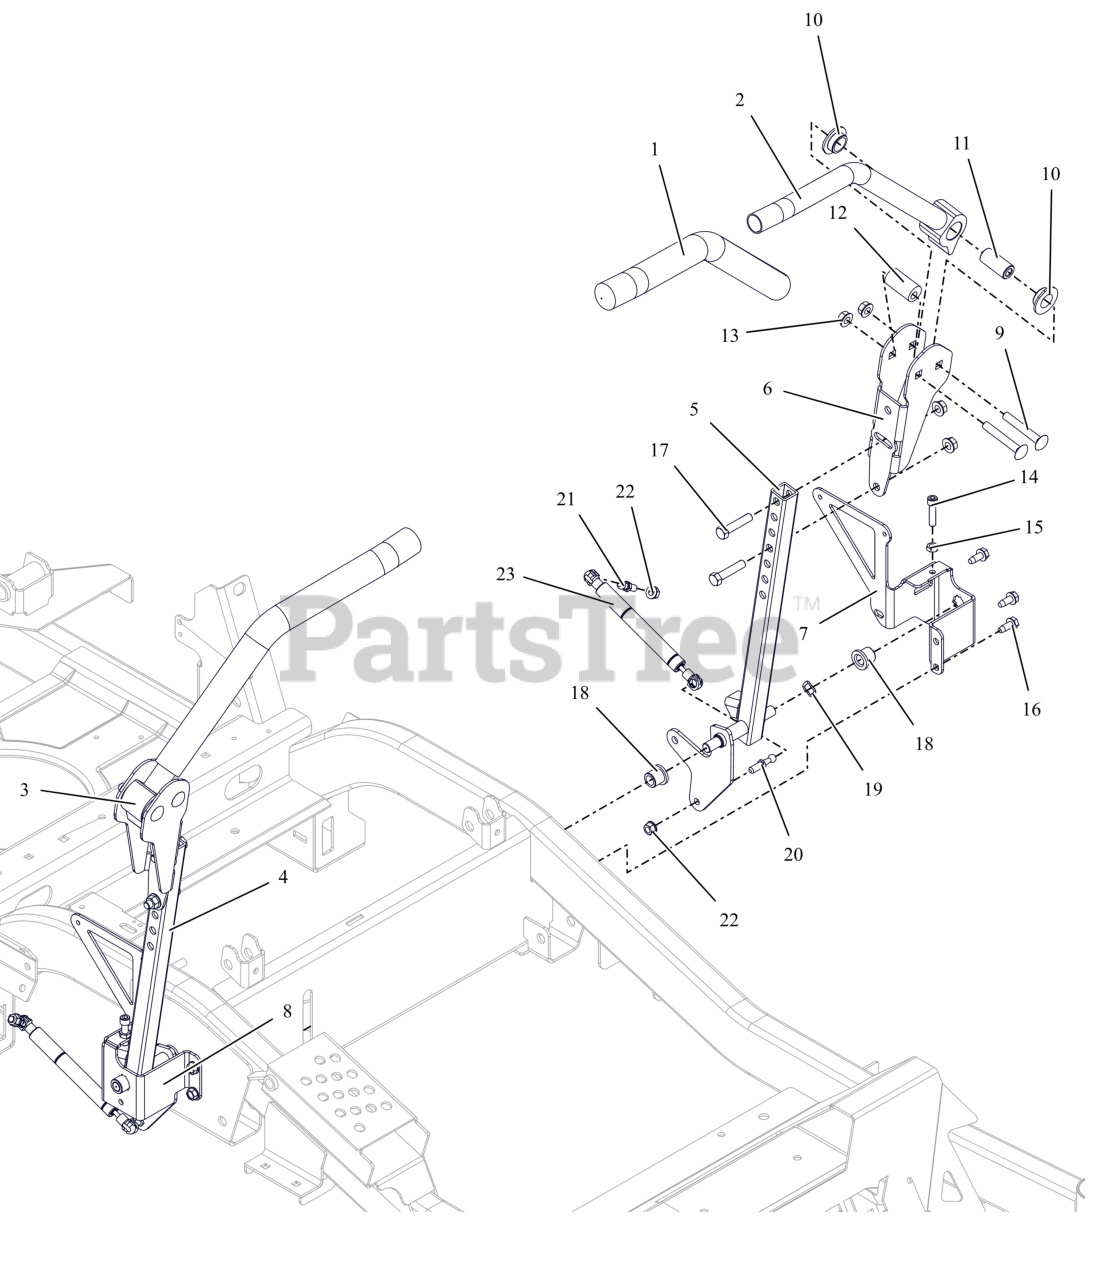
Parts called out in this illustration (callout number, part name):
1	GRIP, HANDLEBAR
2	WLDMT, CONTROL HANDLE (RED)
3	WLDMT, CONTROL HANDLE (RED)
4	WLDMT, STEERING RH (RED)
5	WLDMT, STEERING -LH (RED)
6	BRKT, ADJ UPPER CONTROL ARM (RED)
7	BRKT, STEERING ARM MOUNTING -LH (RED)
8	BRKT, STEERING ARM MOUNTING- RH (RED)
9	BLT, RHSSN.38-16X2.50 G5 ZCC
10	BSHG, FLANGED .762 X 1.48 X .44 IGLIDER
11	SPACER, STEERING ARM
12	BSHG, ECCENTRIC.406X.875X1.625
13	NUT-LK-TOP-FLG .38-16 ZC120
14	SCR, SKH .312-18X1.25 GR8 ZC120
15	NUT-JAM .312-18 G2 ZCC
16	SCR,TAP .312-18X.75 HWH TR ZCC
17	BLT, HEX .38-16X1.75 G5 ZCC
18	BHSG-FLG .500X.750X.750X.125
19	WAVE WASHER .531X.781X.125FH
20	STUD-BALL-THREADED
21	STUD- BALL
22	NUT,LK-CTR-FLG .31-18 GF ZCC
